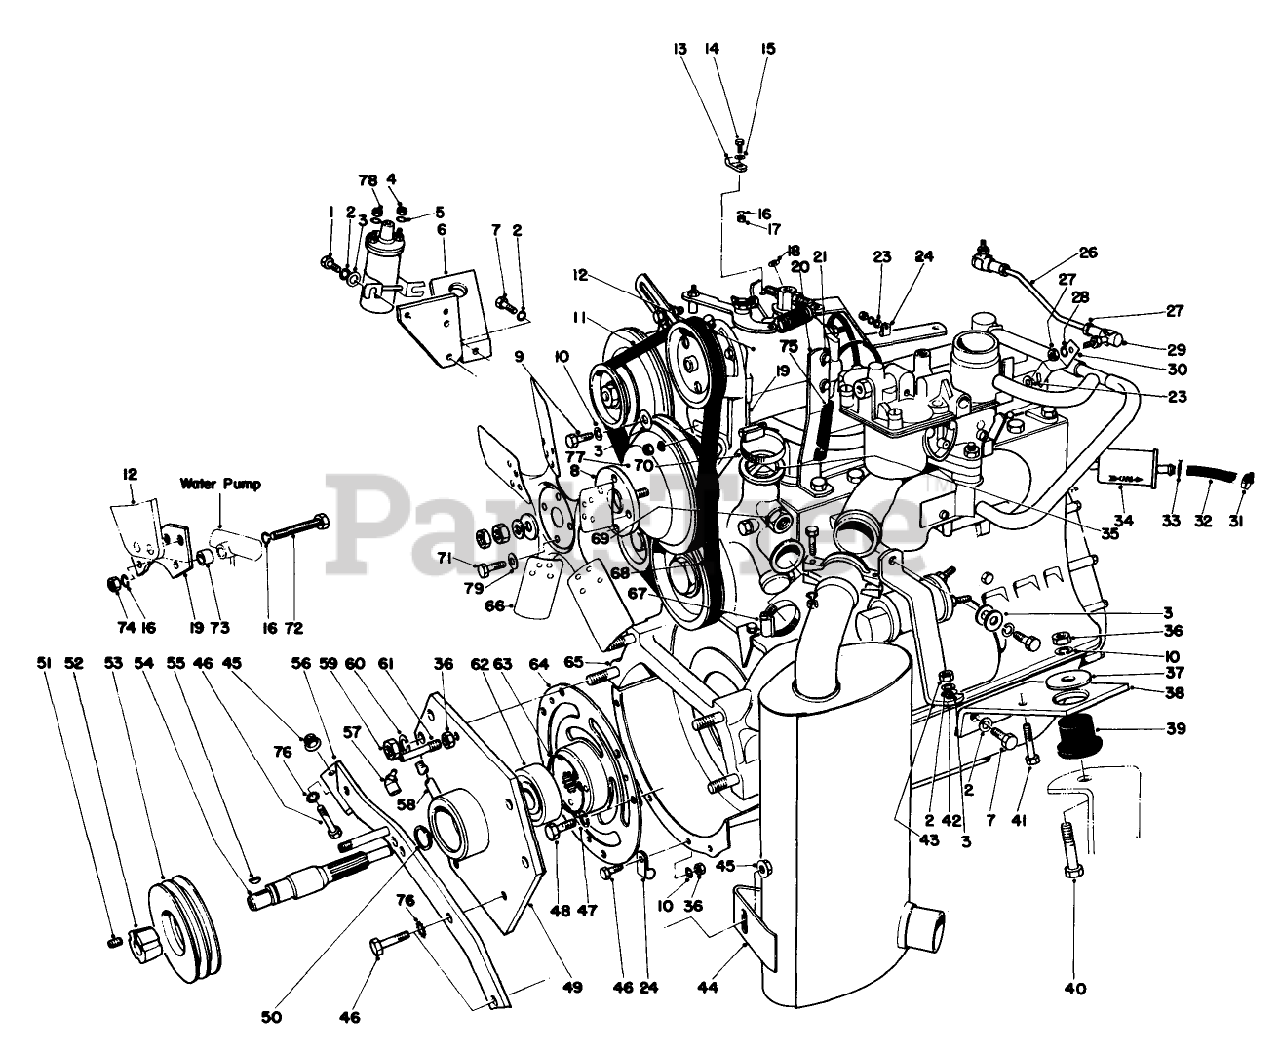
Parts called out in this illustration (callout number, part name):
1	SCREW-HH
2	WASHER-LOCK
3	WASHER-FLAT
4	M5 HEX NUT
5	Metric Lockwasher
6	ENG MOUNT WA B
7	CAPSCREW
8	Spacer
9	SCREW-HH
10	WASHER-LOCK
11	V-BELT
12	GOVERNOR
13	CLAMP-BODEN
14	SCREW-HH
15	WASHER-FLAT
16	WASHER-LOCK
17	NUT-HEX
18	WASHER-FLAT
19	GOVERNOR BRKT
20	SUPPORT BRKT B
21	SCREW
23	WASHER-PLAIN
24	CLAMP-R
26	THROTTLE ROD
27	NUT-HEX
28	WASHER-LOCK/SP
29	BALL JOINT
30	Lever Carburetor
31	CLAMP-HOSE
32	FUEL LINE HOSE
33	CLAMP-HOSE
34	FiIter Gas
35	THERMOSTAT (F/W)
36	NUT-HEX
37	Washer
38	ENGINE MOUNT B
39	RUBBER MOUNT
40	SCREW-HH
41	SCREW-HH
42	ENG MT BRKT B
43	NUT-HEX
44	MUFFLER
45	NUT-HHF, WHIZ
46	SCREW-HH
47	LOCKWASHER
48	Metric Capscrew
49	BEARING MOUNT
50	RING-SNAP
51	SCREW-SET
52	Bushing-Taper Lock (Incl. Ref . #51)
53	DRIVE PULLEY
54	ENGINE OUTPUT SHAFT
55	KEY-WOODRUFF
56	FRONT ENGINE SUPT WA
57	FITTING-GREASE
58	PIPE NIPPLE
59	NUT-HEX
60	WASHER-LOCK/INT
61	STUD-RETAINER, BELT
62	Bearing
63	RING-SNAP, INTERNAL
64	ENG ADAPTOR DRIVE ASM
65	Engine-Continental (Model No. R08-D15-2002
66	15 INCH FAN
67	CLAMP-HOSE
68	V-BELT
69	TEMP GAGE ADAPTER
70	CLAMP-HOSE
71	Screw-HH
72	SCREW-HH, M6
73	SPACER
74	NUT-HEX
75	SUPT BRKT TRIM
76	WASHER-LOCK
77	PULLEY
78	NUT-HEX
79	FLAT WASHER
80	Capscrew
81	WASHER-LOCK, SPRING
82	MUFFLER BRKT
